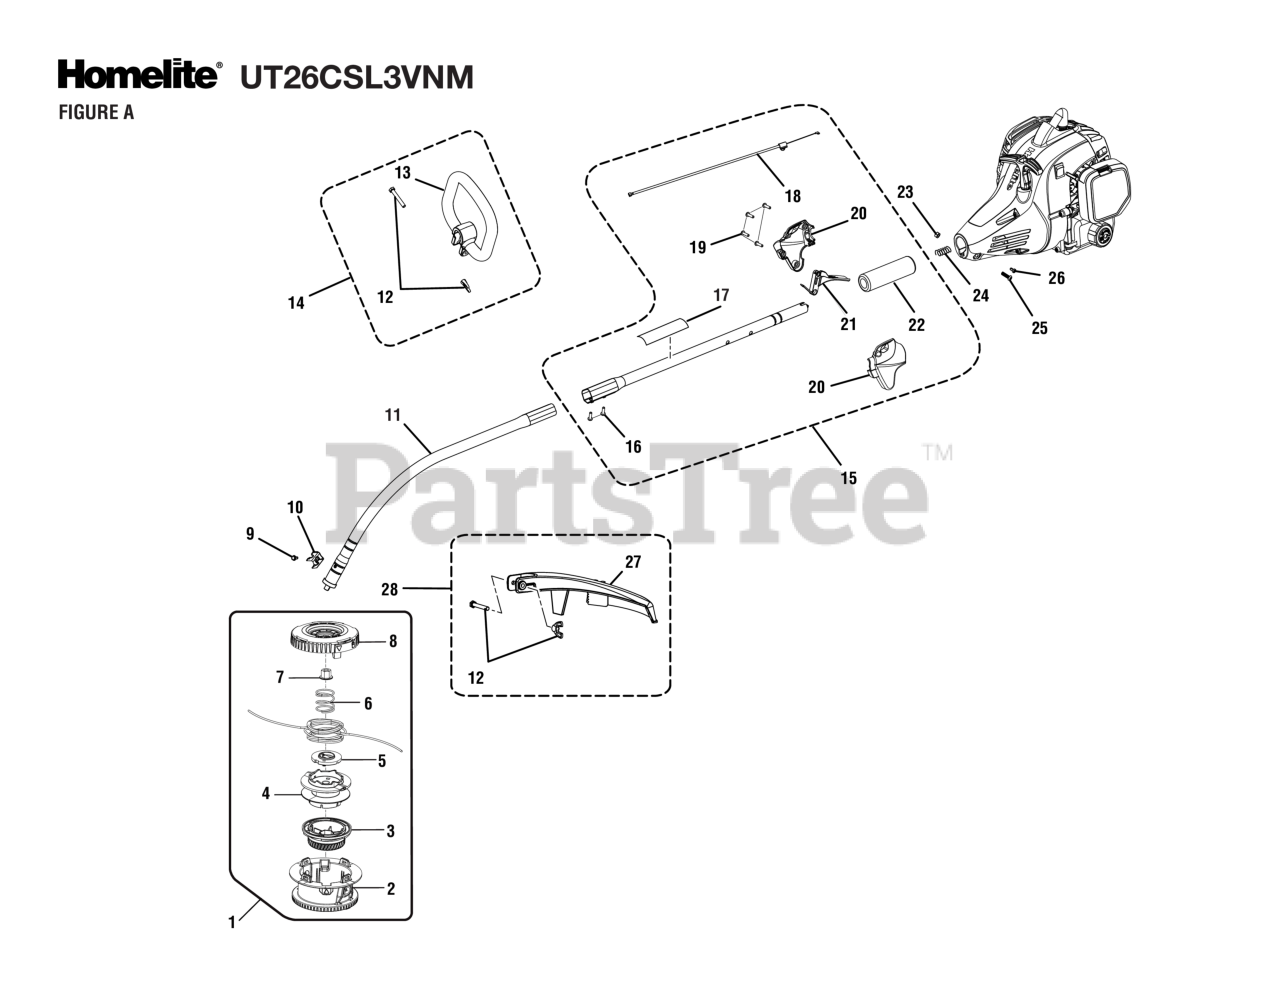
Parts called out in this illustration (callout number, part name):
1	Trimmer Head Assembly (Inc. Key Nos. 2-8)
2	Bump Head
3	Bump Knob (Gray)
4	Spool Assembly
5	String Guide
6	Compression Spring
7	Flange Nut (M8)
8	Locking Assembly
9	Screw (#10-32 x 3/8 in., Hex Washer Hd. S.T.)
11	Lower Boom Assembly
12	Fastener Parts Kit
13	Front Handle
14	Front Handle Assembly
15	Boom Assembly
16	Set Screw (M5 x 10 mm, Hex Soc. Hd.)
17	Icon Warning Label
18	Throttle Cable
19	Screw (M4 x 20 mm, T20 Torx Pan Hd. T.Fl.)
20	Trigger Handle Assembly
21	Throttle Trigger
22	Rubber Grip
23	Hex Nut (M6.3 x 1)
24	Compression Spring
25	Screw (M6 x 20 mm, T27 Torx Button Hd.)
26	Screw (M4 x 8 mm, T25 Torx Pan Hd. T.F.)
27	Grass Deflector
28	Grass Deflector Assembly
